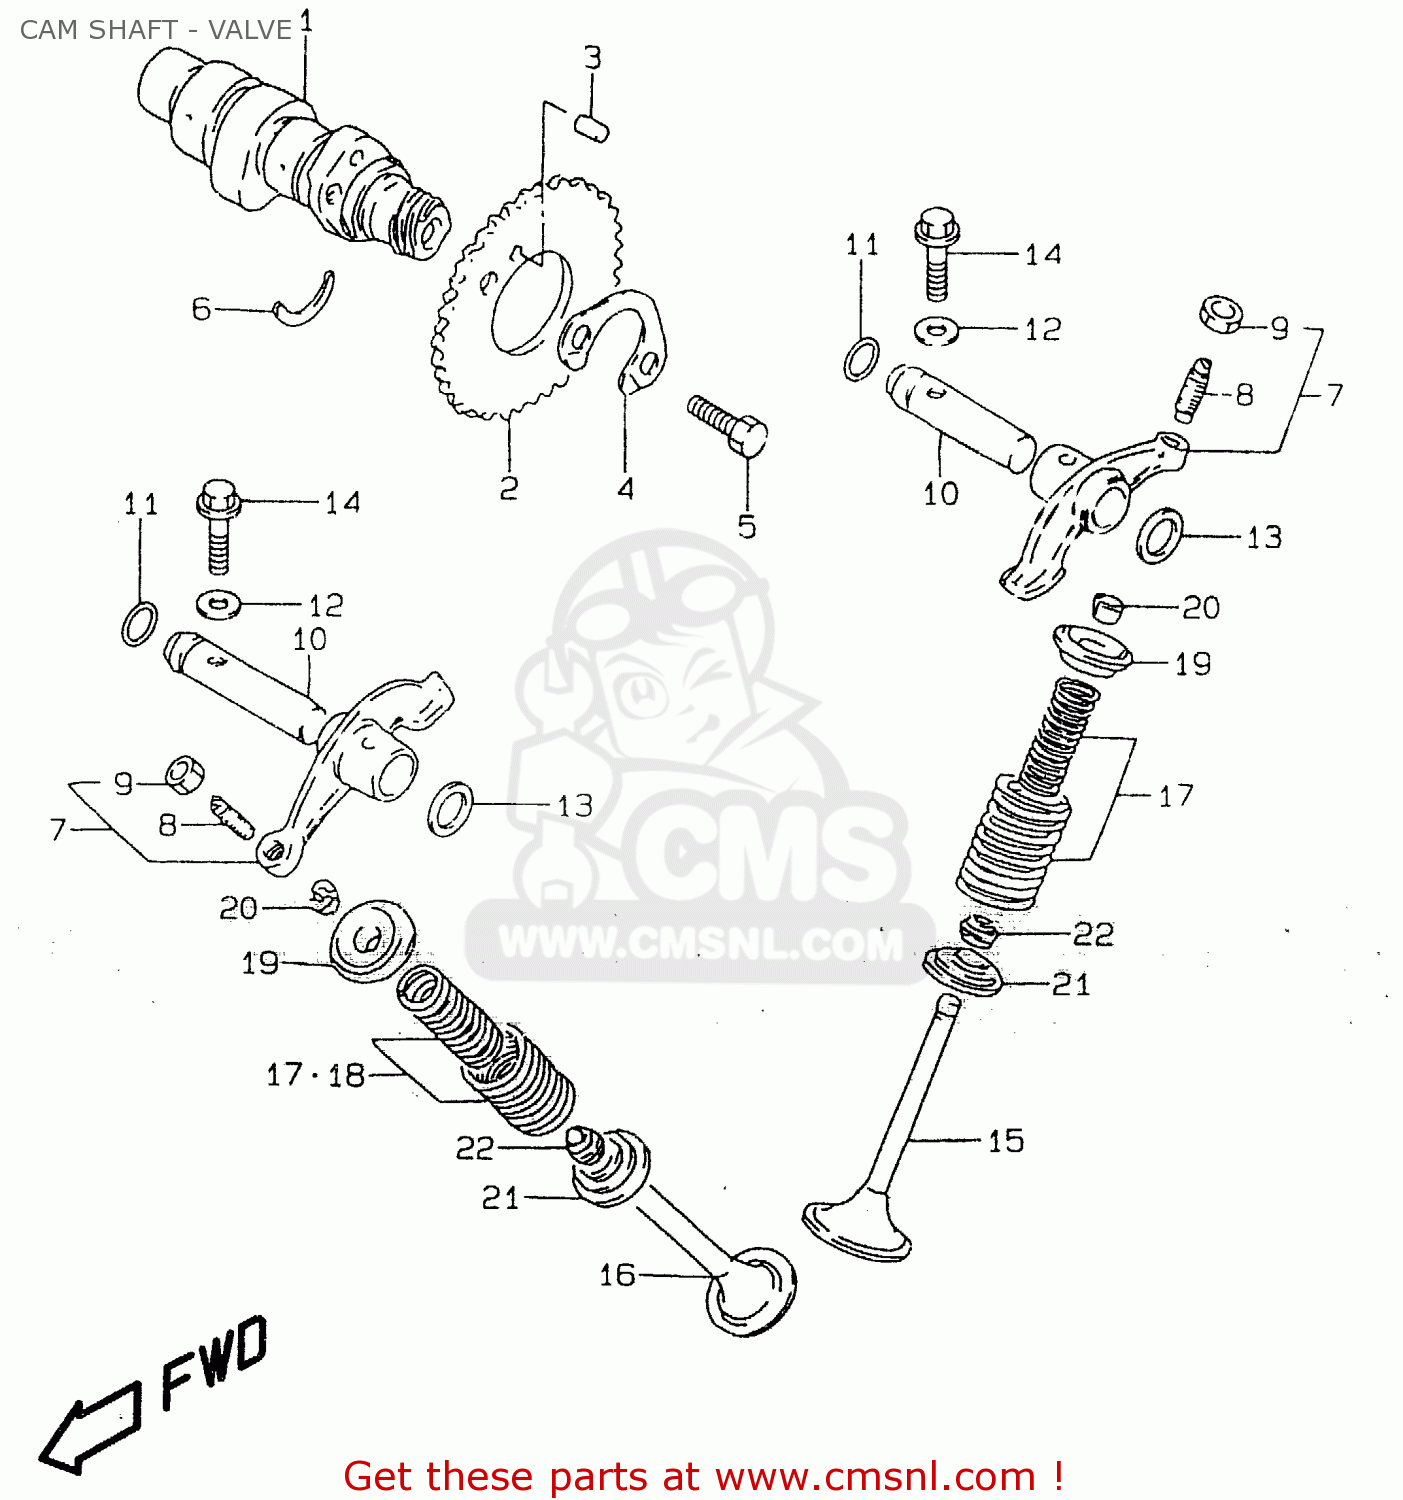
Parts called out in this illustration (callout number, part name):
1	CAM SHAFT
2	SPROCKET,CAMSHAFT
3	PIN(5X8)
4	WASHER,SPROCKET
5	BOLT(6X10.5)
6	C RING
7	ARM ASSY,VALVE ROCKER
8	SCREW,TAPPET ADJUSTING
9	NUT,ADJUSTING SCREW
10	SHAFT,VALVE ROCKET
11	O RING(D:1.9,ID:8.6)
12	GASKET(5.8X13X1.2) (NAS)
13	WASHER
14	BOLT
15	VALVE,INTAKE
16	VALVE,EXHAUST
17	SPRING SET,VALVE
18	SPRING SET,VALVE
19	RETAINER,VALVE SPRING
20	COTTER,VALVE
21	SEAT,VALVE SPRING
22	SEAL,OIL(5.5X11X8.2)
